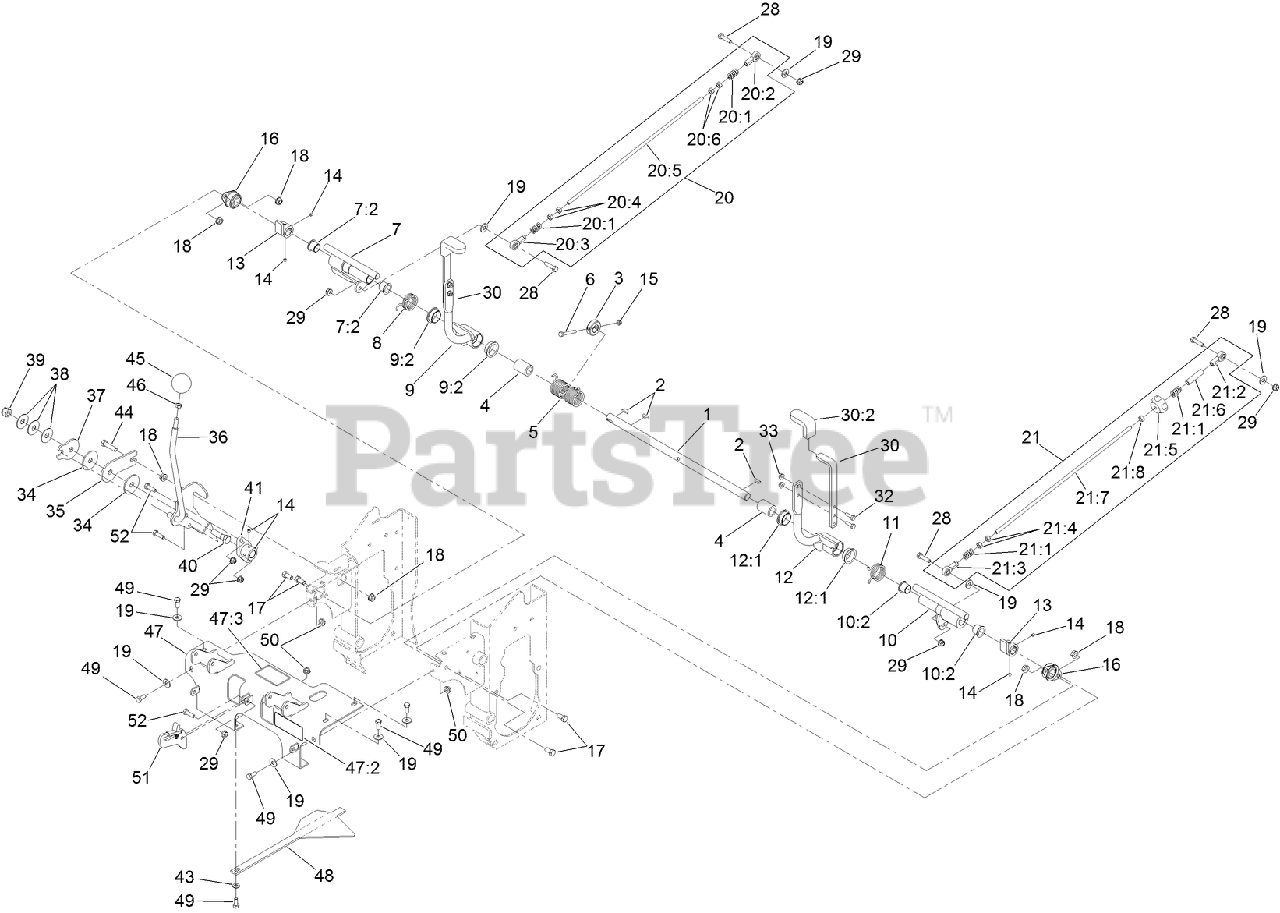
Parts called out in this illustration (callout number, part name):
1	SHAFT-CONTROL, SPEED
2	KEY-WOODRUFF
3	STOP-HUB, CENTER
4	BUSHING-PLASTIC
5	SPRING-TORSION, DOUBLE
6	SCREW-HH
7	RH CONTROL HUB ASM
7:2	BEARING-FLANGE, IGLIDE
8	SPRING-TORSION, RH
9	RH STEERING HANDLE ASM
9:2	BEARING-FLANGE, IGLIDE
10	LH CONTROL HUB ASM
10:2	BEARING-FLANGE, IGLIDE
11	SPRING-TORSION, LH
12	LH STEERING HANDLE ASM
12:1	BEARING-FLANGE, IGLIDE
13	HUB-SPEED CONTROL
14	SCREW-SET
15	NUT-LOCK, NI
16	BEARING-FLANGE, SIDE
17	SCREW-HH
18	NUT-HHF, WHIZ
19	WASHER-FLAT
20	RH PUMP LINKAGE ASM
20:1	SPRING-COMPRESSION
20:2	BALLJOINT-RH
20:3	BALLJOINT-LH
20:5	ROD-LINKAGE, STEERING
20:6	NUT-HEX
21	LH PUMP LINKAGE ASM
21:1	SPRING-COMPRESSION
21:2	BALLJOINT-RH
21:3	BALLJOINT-LH
21:5	KNOB-TRACKING
21:6	SPACER
21:7	ROD-LINKAGE, STEERING
21:8	NUT-HEX
28	SCREW-HH
29	NUT-HF, NI
30	HANDLE ASM
30:2	GRIP-HANDLE, STEERING
32	SCREW-HH
33	NUT-HF
34	DISC-FRICTION
35	PLATE-FRICTION, SPEED CONTROL
36	LEVER-SPEED CONTROL
37	PLATE-FRICTION, SPEED CONTROL
38	WASHER-DISC, SPRING
39	NUT-HEX
40	SCREW-HH
41	HUB-CONTROL, SPEED
43	WASHER-PLAIN
44	SCREW-HH
45	KNOB-BALL, SPEED CONTROL
46	NUT-JAM
47	CONSOLE ASM
47:2	DECAL-DANGER, DRIVELINE
47:3	DECAL-MOTOR, WHEEL
48	GUIDE-PLENUM
49	SCREW-HH
50	NUT-HF
52	SCREW-HH
